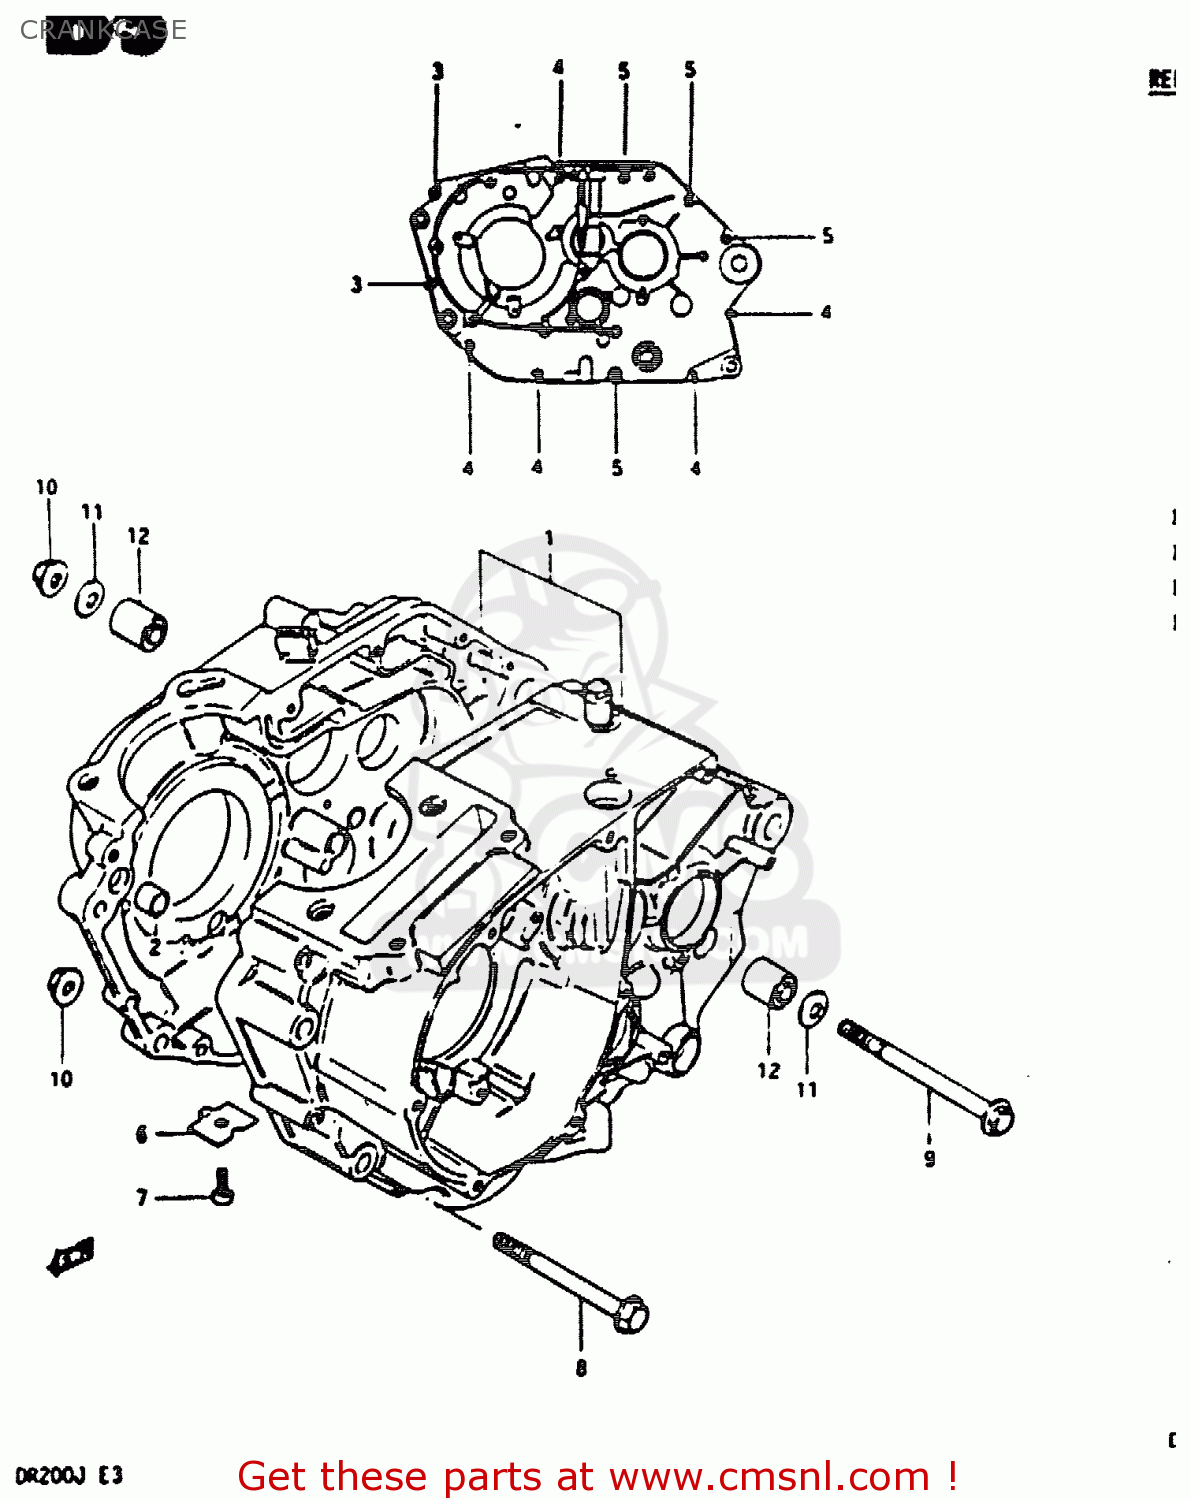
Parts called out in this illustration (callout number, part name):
1	CRANKCASE SET
2	PIN
3	BOLT
4	BOLT (6X60)
5	BOLT (6X75)
6	PLATE,OIL GALLERY PLUG
7	BOLT
8	BOLT(8X80)
9	BOLT L:115
10	NUT
11	WASHER
12	BUSH(8.4X18X16)
